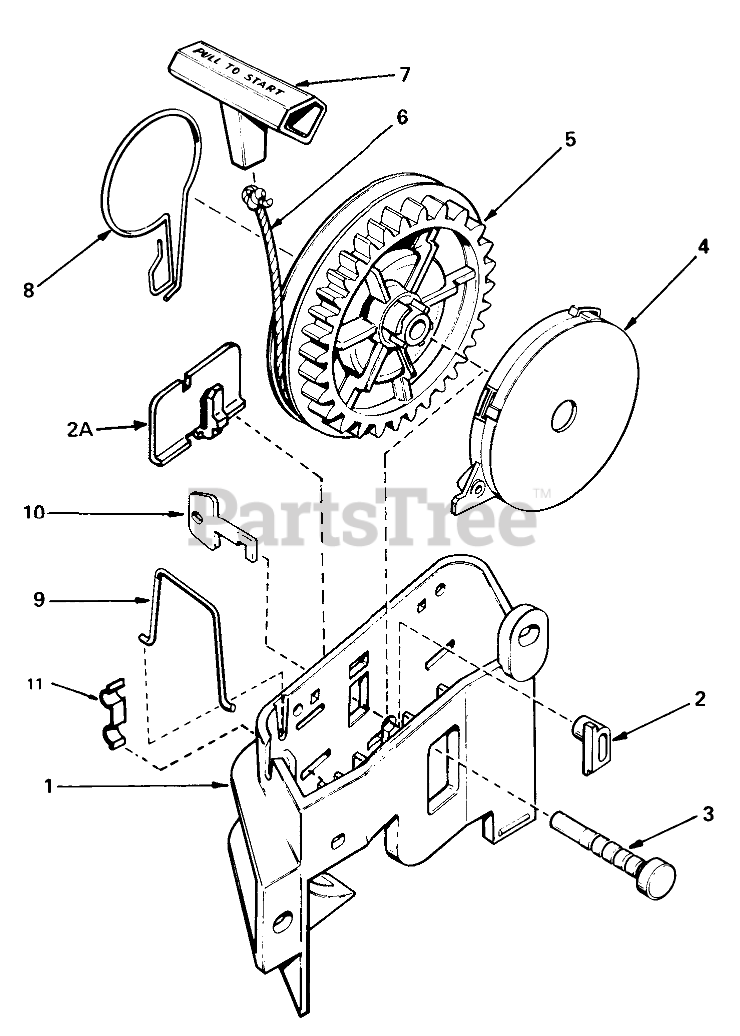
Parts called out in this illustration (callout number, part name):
1	Bracket Starter
2	Pawl, Locking Not used on all engine models)
2A	Clip, Starter Bracket (Used On Starters Not Equipped With Pawl, Ref. No. 2)
3	Pin-Pulley
4	Spring Assy., Rewind (Incl. Ref. #3)
6	Rope Starter (Length 65" & 9/64" Dia.)
7	Handle-Starter
9	Clip-Rope
10	Key (Not Used On All Engine Models
11	Washer-Thrust
